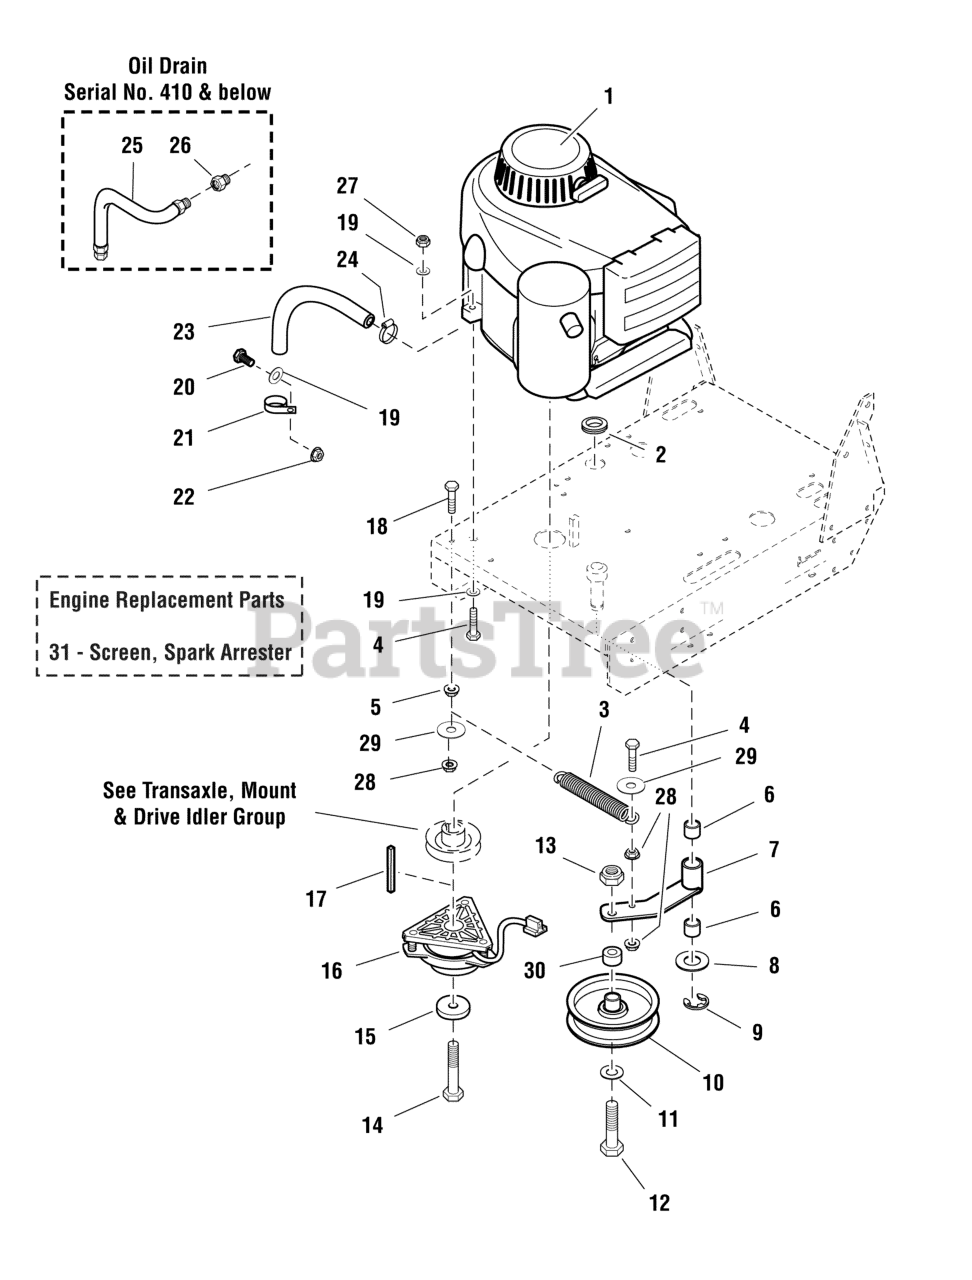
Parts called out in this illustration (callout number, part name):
1	FUEL FILTER
1	OIL FILTER (49065-2078)
2	GROMMET, 7/8
3	SPRING, Extension
4	BOLT, 5/16-18 X 1-1/2" GD5 YZ
5	NUT, 5/16-18 HEX SERRATED FLANGE (LARGE)
6	BUSHING, BRASS, 3/4 X 1 X 1
7	DECK DRIVE IDLER ARM
8	WASHER, 3/4 SAE
9	C-CLIP
10	IDLER PULLEY
11	WASHER, 1/2 SAE
12	BOLT, 1/2-13 X 2-1/2" GD5 CZ
13	NUT, 1/2-13 HEX NYLON LOCK
14	BOLT, CRANKSHAFT, 7/16"X2.75
15	SPACER, .45 x 1.62 x .37
16	CLUTCH, OGURA, 74 ft lbs - 1"
17	KEY, 1/4 SQ. X 2
18	BOLT, 5/16-18 X 2" GD5 YZ
19	WASHER, 5/16" SAE
20	BOLT, 5/16-18 X 3/4 GD5
21	CLAMP
22	NUT, 5/16-18 HEX SERRATED FLANGE (SMALL)
23	HOSE, 10-1/2"
24	CLAMP, #6 HOSE, STAINLESS
25	OIL DRAIN HOSE
26	ADAPTER, Oil Drain
27	NUT, 5/16-18 Hex Nylon Lock
28	NUT, 5/16-18 Hex Nylon Flange
29	WASHER, 5/16" USS
30	SPACER, .52 x 1.00 x .38
31	SCREEN, SPARK ARRESTER-KAWI 13, 17, 19HP
